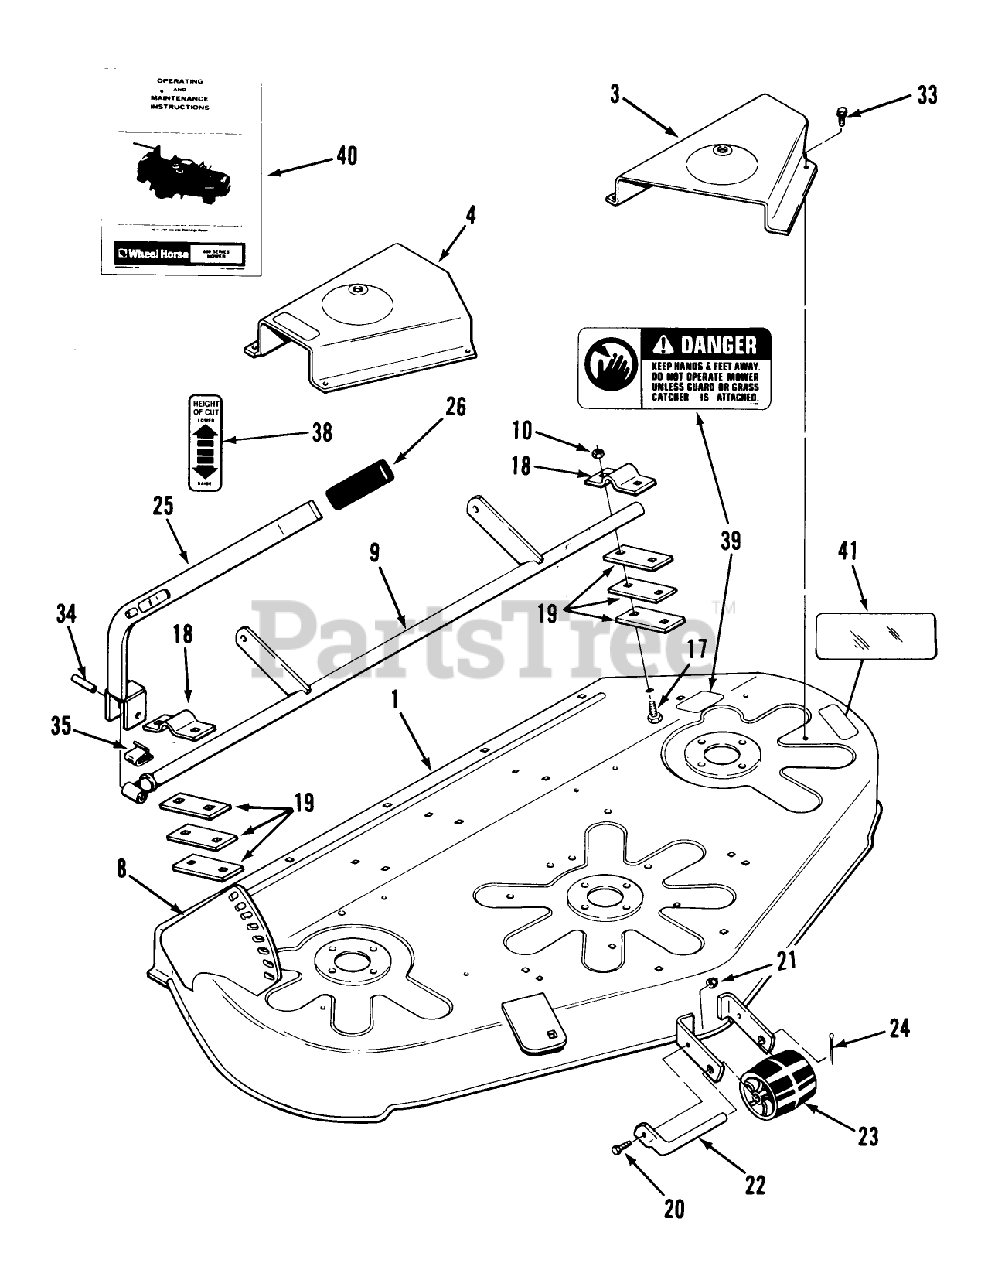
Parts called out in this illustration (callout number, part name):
8	QUADRANT 42RY MOWER
9	Lift Support
18	CLAMP
22	ROLLER-SHAFT
33	Bolt
34	SPIROL PIN 3/8X1 1/2
35	CLIP-SPRING
38	DECAL-HOC
40	Operator-s Manual
41	DECAL-OVERLAY
